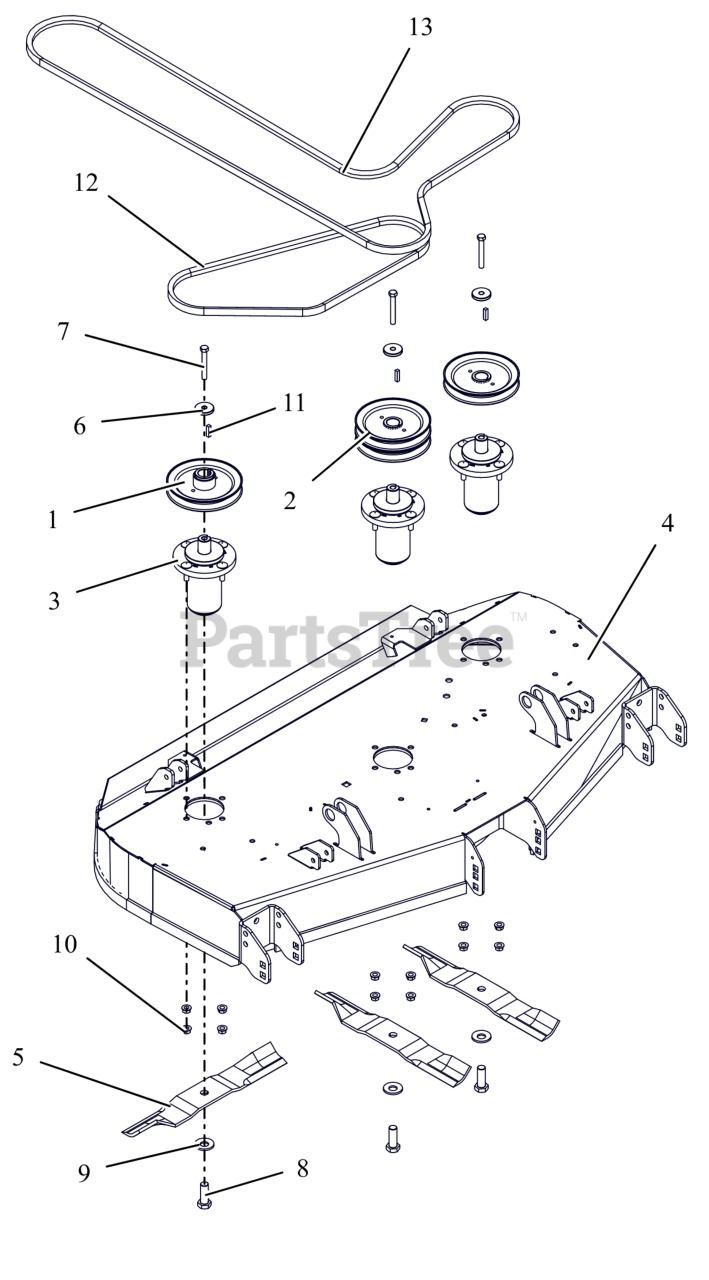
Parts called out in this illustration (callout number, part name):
1	PULLEY, SINGLE -1.000 ID X 6.000 OD
2	PULLEY- DOUBLE
3	ASM, MAINT FREE ALUM SPINDLE
4	WLDMT, 48" RD DECK
5	BLADE, 16.19" MOWER (HI-LIFT)
6	RETAINER, SHEAVE
7	BLT, HEX .38-16X2.75 G8 ZCC
8	BLT, HEX .62-18X1.75 G8 ZCC
9	WSHR-BLVL .669X1.535X.138
10	NUT-LK-CTR-FLG .375-16 GF ZCC
11	KEY, SQ .25X.25X1.00 RC 40-50
12	V-BELT, B-COGGED
13	V-BELT, HB SECTION
